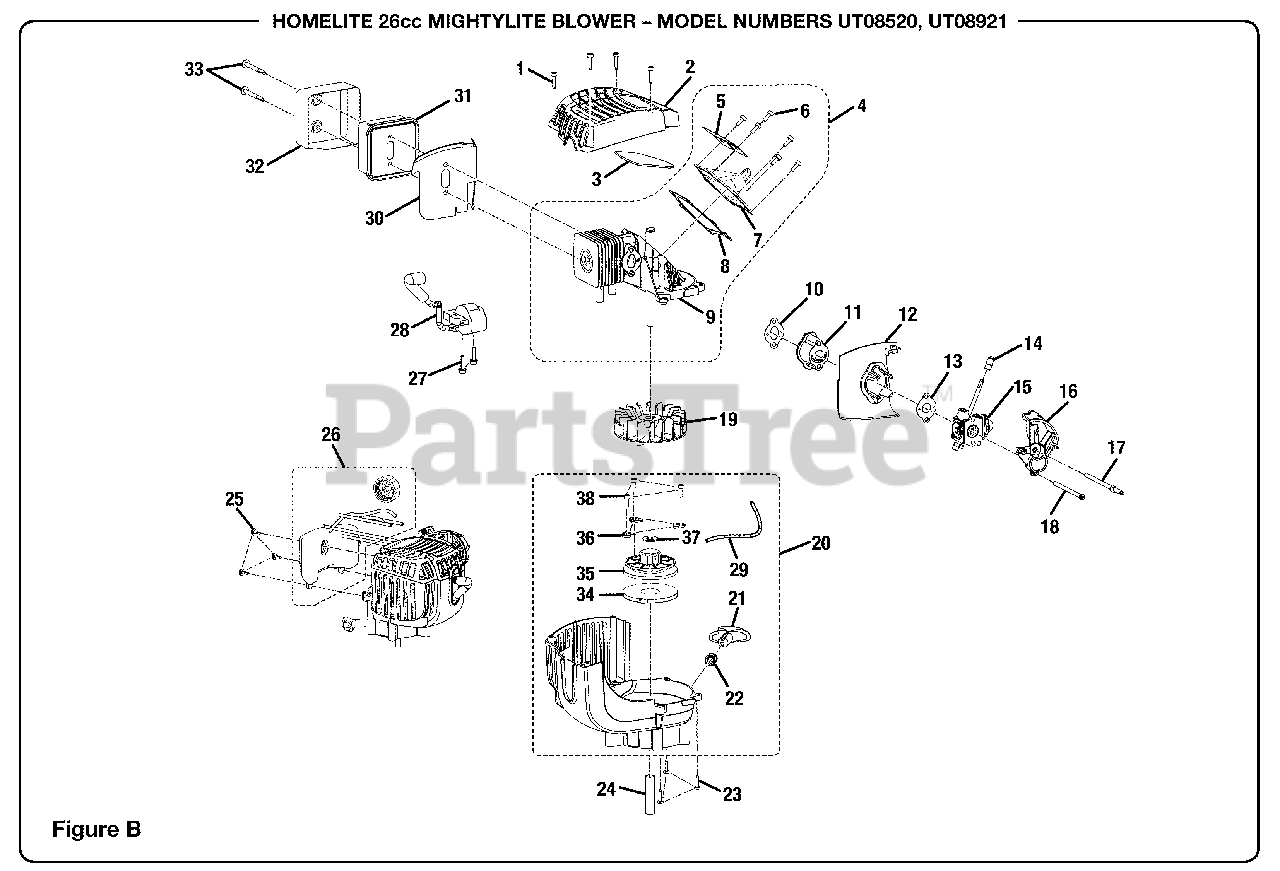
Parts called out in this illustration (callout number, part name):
1	Screw (M4 x 18 mm)
2	Upper Housing
3	Heat Shield Gasket
4	Short Block Assembly
5	Cylinder Heat Shield
6	Screw (M4 x 12 mm)
7	Crankcase Cover
8	Crankcase Cover Gasket
9	Cylinder
10	Intake Gasket
12	Baffle Plate
13	Carburetor Gasket
14	Throttle Lever
15	Carburetor
16	Air Box Base
17	Double Sided Hex Bolt
18	Screw (M5 x 70 mm)
19	Flywheel Assembly
20	Lower Housing with Starter Assembly
21	Starter Grip
23	Screw (M4 x 16 mm)
24	Crankshaft Spacer
25	Screw (M4 x 10 mm Shoulder)
26	Fuel Tank with Cap Assembly
27	Screw (M4 x 9 mm)
28	Ignition Module
29	Starter Rope
30	Gasket Muffler
31	Muffler Assembly
32	Heat Shield
33	Screw (M4 x 18 mm)
34	Spring & Container Assembly
35	Starter Pulley
36	Pulley Retainer
37	Flat Washer
38	Screw (M4 x 14 mm)
